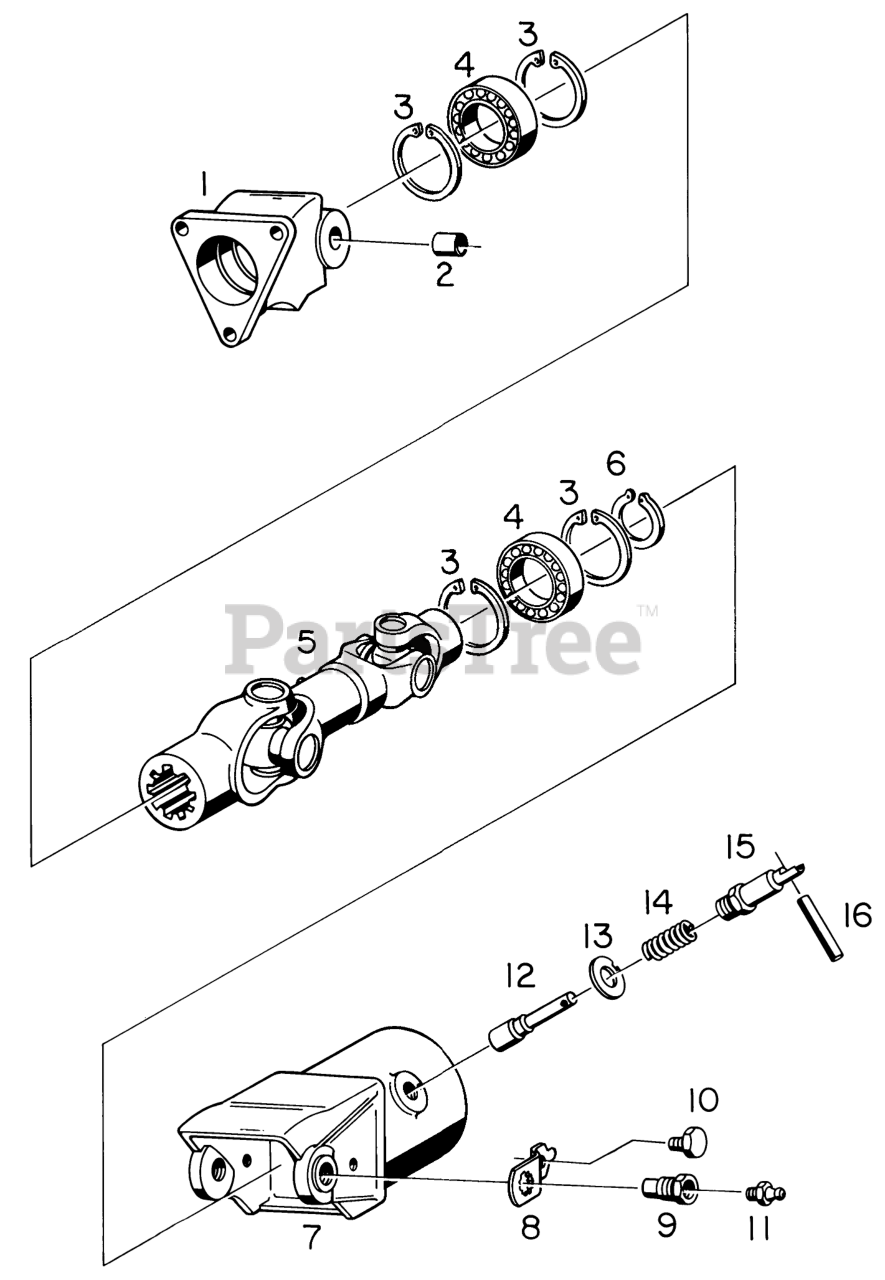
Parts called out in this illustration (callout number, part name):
1	Flange
2	Needle Bearing
3	Retaining Ring
4	Ball Bearing
5	PTO Extension Shaft
6	Retaining Ring
7	Rear Housing
8	Lock Plate
9	Pivot Bolt
11	Grease Zerk
12	Lock Rod
13	Washer (Special)
14	Spring
15	Bushing
16	Rollpin
